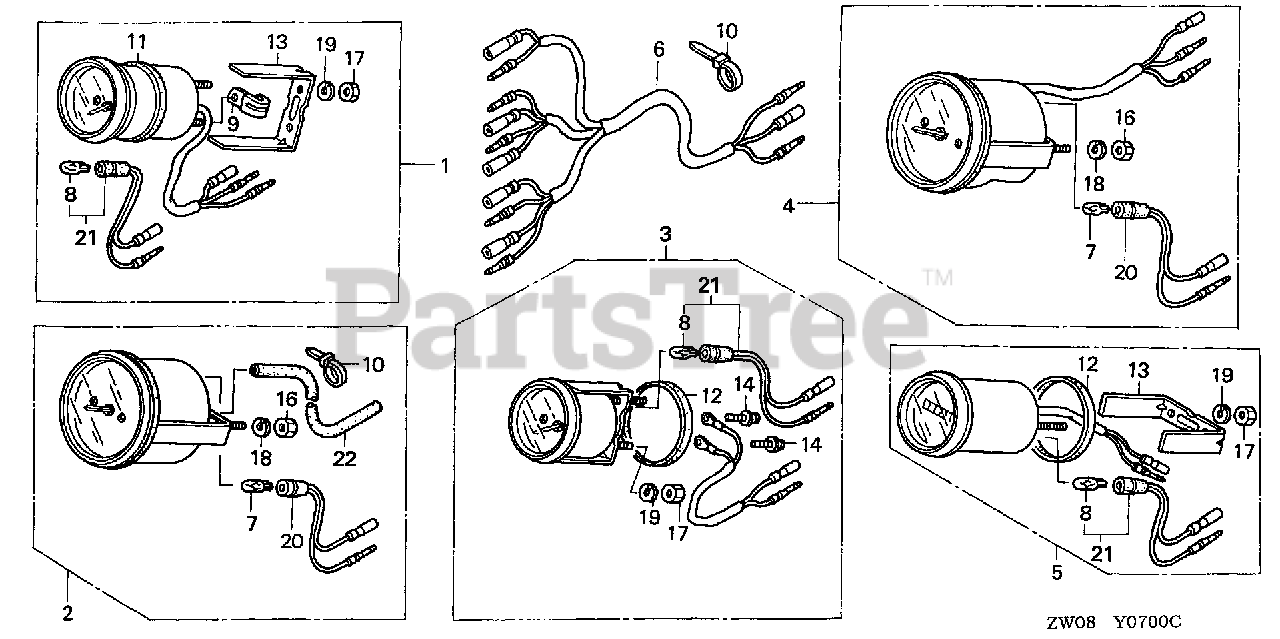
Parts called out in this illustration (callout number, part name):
1	METER KIT, TRIM (WHITE)
1	METER KIT, TRIM (B) (BLACK)
2	SPEEDOMETER KIT (WHITE) (NOT AVAILABLE)
2	METER KIT, SPEED *NH1D* (B) (BLACK)
3	METER KIT, VOLT (WHITE)
3	METER KIT, VOLT *NHA85* (B) (BLACK)
4	METER KIT, TACHO
4	METER KIT, TACHO (B)
5	METER KIT, HOUR (WHITE) (NA USE ALT:39700-ZW5-000ZA)
5	METER KIT, HOUR (B) (NA USE ALT:39700-ZW5-000ZA)
6	HARNESS ASSY., METER (B)
7	BULB, WEDGE BASE (T10) (12V 1.7W) (STANLEY)
8	BULB, WEDGE BASE (12V1.7W) (TOSHIBA)
9	CLAMP
10	BAND, SELF-LOCK
11	GASKET (TO 1015209) (FROM 1015210)
12	GASKET
13	BRACKET (TO 1015209) (FROM 1015210)
14	SCREW-WASHER (3X22)
16	NUT, HEX. (5MM)
17	NUT, HEX. (4MM)
18	WASHER, SPRING (5MM)
19	WASHER, SPRING (4MM)
20	SOCKET
21	SOCKET
22	TUBE, SPEED METER (4X7X8000)
